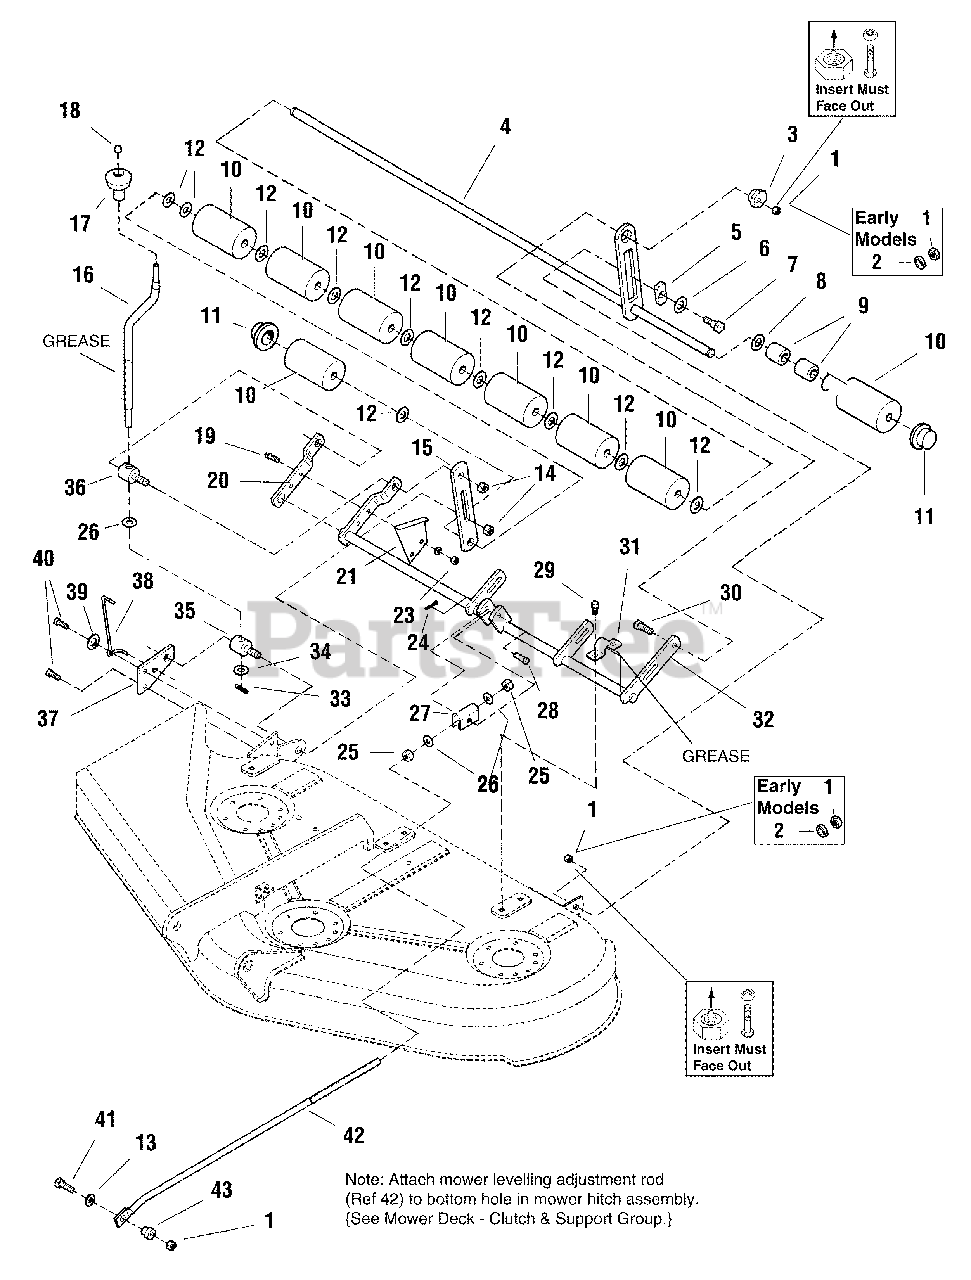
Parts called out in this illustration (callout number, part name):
1	NUT, Hex, 3/8-16 (Early Models)
1	NUT, Hex Alum Insert Lock, 3/8-16 (Later Models)
2	WASHER, Lock, 3/8 (Early Models)
3	NUT, Hex Adjusting, .99 DIA .687
4	SHAFT ASSEMBLY, Roller, 44" (Includes Ref. Nos. 8, 9 & 11)
6	WASHER, Plain, 1/2
7	BOLT, Shoulder, 3/8-16 X 1.34
8	WASHER, 5/8
9	SPACER, .66 ID
11	NUT, Push
12	WASHER, 5/8
13	WASHER, 3/8
14	NUT, Hex, Flange, Lock, 1/2-13
15	BAR, Roller
16	CRANK, Cutting Height
17	KNOB, Height Crank
18	PAL NUT
19	CAPSCREW, Hex Head, 5/16-18 x 1-1/4
20	ARM, Rear, Mower, RH
21	BRACKET, Cutting Height
23	NUT, Hex, 5/16-18
24	PIN, Hair Clip
25	NUT, Hex, Jam, 1/2-13
26	WASHER, 33/64
28	PIN, Clevis
29	CAPSCREW, Hex Head, Taptite, 5/16 -18 x 3/4
30	CARRIAGE BOLT, 3/8-16 x 1-1/2
31	STRAP, Mower Arm Assembly
32	ARM ASSEMBLY, Mower
33	PIN, Roll, 1
34	WASHER, Detent
36	TRUNNION, Threaded
37	PLATE, Mower Support
38	INDICATOR, Cutting Height
39	WASHER, Flat, 5/16
40	CAPSCREW, Hex Head, Taptite, 5/16-18 x 1-1/4
41	CAPSCREW, Hex Head, 3/8-16 x 1-3/4
42	ROD, Adjustment
